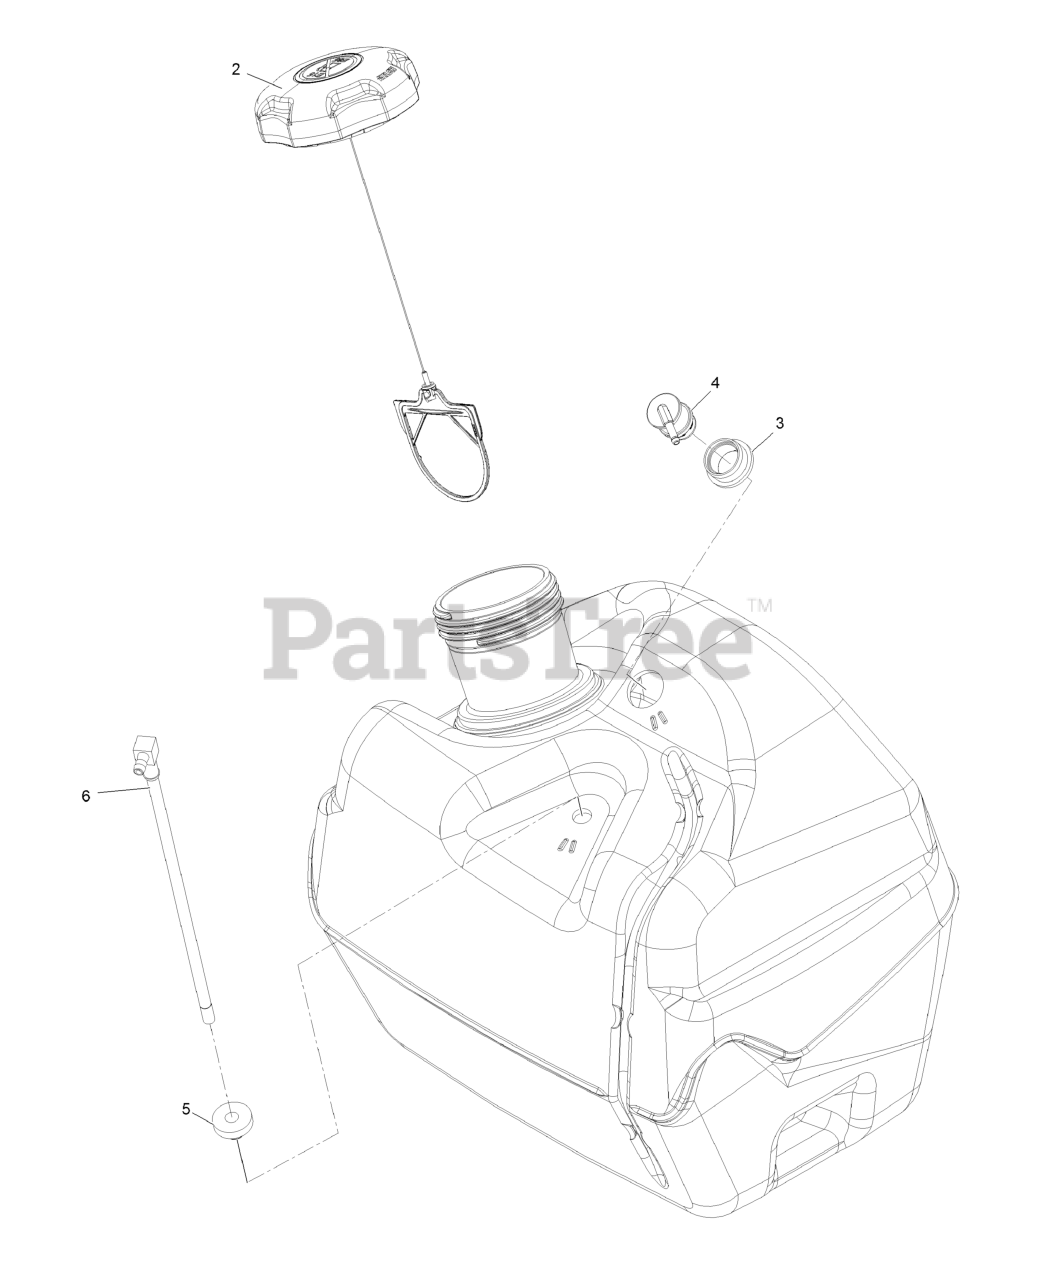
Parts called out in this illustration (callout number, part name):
2	CAP-FUEL, RATCHETING
3	GROMMET
4	VALVE-VENT, FUEL
5	BUSHING
6	FITTING, FUEL W/LINE AND SCREEN
